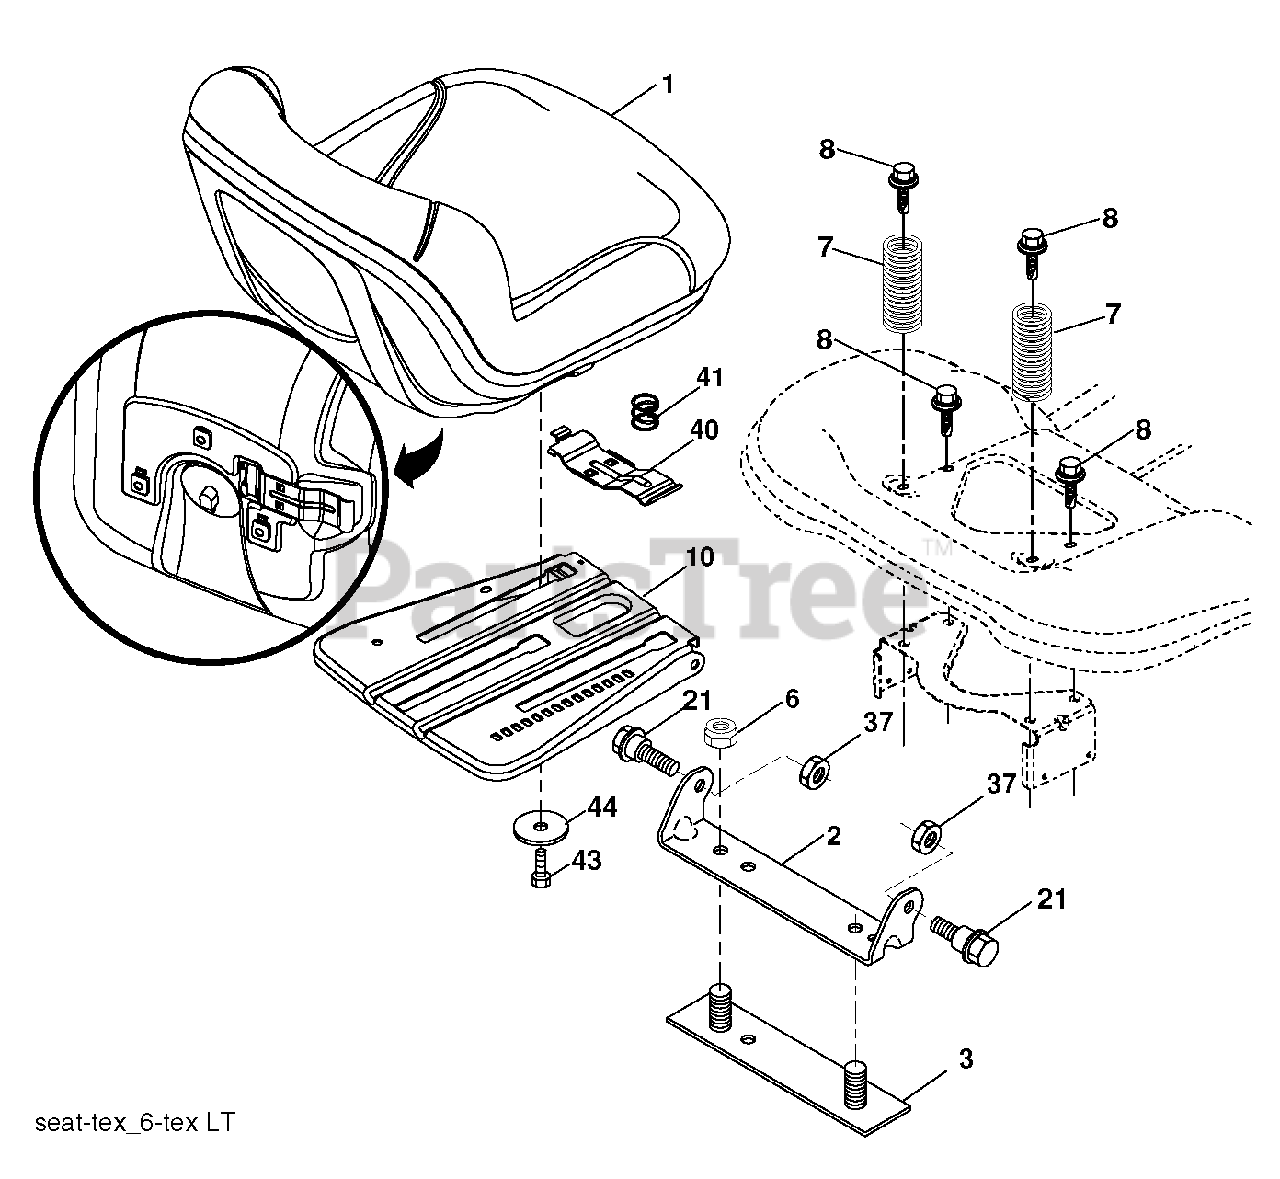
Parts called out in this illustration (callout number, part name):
1	SEAT.TH150.MS498.GRY.HUSQ.TEX
2	BRKT.PIVOT.FENDER
3	STRAP
6	NUT
7	SPRING COMPRESSION
8	BOLT, 5/16-18 X 1 3/4
10	PAN.ASM.SEAT.3PT
21	BOLT.SHOULDER.5/16-18
37	NUT.71038.31-18.HEX.NYLOCK
40	HANDLE.SLIDE.SEAT.TEX.BLACK
41	SPRING.LATCH.SEAT.TEX
44	WASHER 13/32 X 2-3/8 X 12GA
